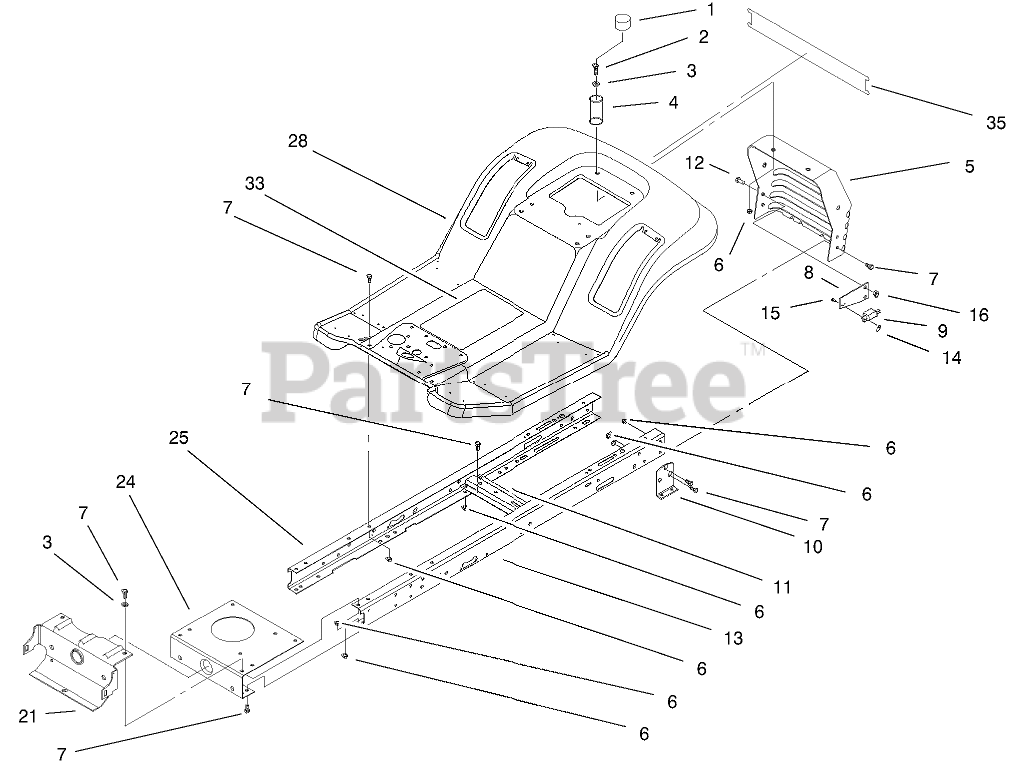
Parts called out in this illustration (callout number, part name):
1	CAP-PROTECTOR
2	SCREW-HH
3	WASHER-PLAIN
4	SPRING-COMPRESSION
5	SUPPORT-SEAT/REAR HITCH
6	NUT-LOCK, NI
7	SCREW-HH
8	PLATE-SWITCH
9	SWITCH-POLE, SINGLE
10	BRACKET-TRANSAXLE, MOUNTING
11	BRACKET-IDLER PIVOT
12	SCREW-HH
13	RAIL-FRAME, LH
14	NUT-LOCK
15	SCREW-SHH
16	NUT-LOCK, NI
21	SUPPORT-FRONT, AXLE
24	PLATE-MOUNTING, ENGINE
25	RAIL-FRAME, RH
28	REAR BODY ASM
33	DECAL-INSTRUCTION
35	DECAL-REAR, BODY
